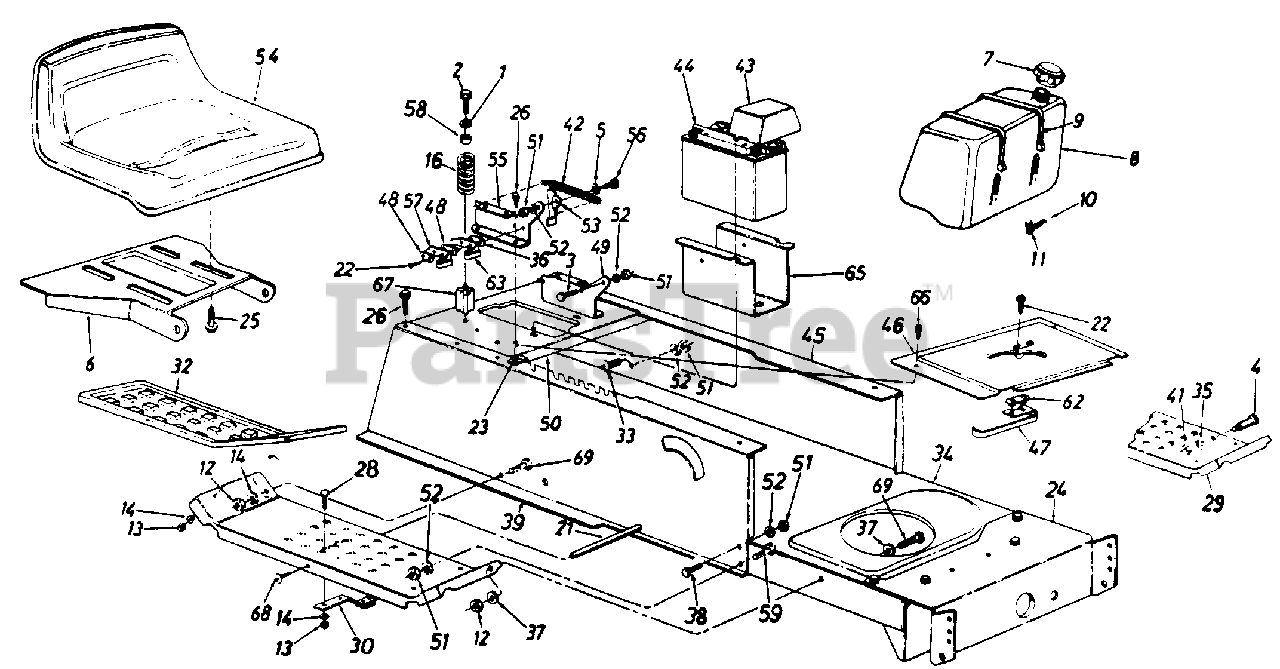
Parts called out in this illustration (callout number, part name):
1	Fl-Wash. .344" I.D. x .875"
2	Hex Wash. Hd. Tap Scr. 5/16-18 x 3.25" Lg.
3	Shld. Bolt .437" Dia. x .162"
4	Shld. Bolt .50" Dia. x .84"
5	Spr. Wash. .445" I.D. x .75
6	Seat Pivot Bracket
7	Fuel Cap
8	Fuel Tank
9	Tie Strap
10	Fuel Line
12	Hex Nut 1/4-28 Thd.
13	Hex Nut 1/4-20 Thd.
14	L-Wash. 1/4" I.D.
16	Compression Spring
21	Running Board Rod
22	Hex Wash. Hd. AB-Tap Scr. #8 x .50" Lg.
23	Speed Nut #10Z
24	Front Pivot Brkt.
25	Hex Tap Scr. 3/8-16 x .75"
26	Hex Wash. Hd. AB-Tap Scr. 5/16 x .75" Lg.
28	Carriage Bolt 1/4-20 x .62"
29	Running Board (R.H. & L.H.)
30	Blade Brake Ass'y.
32	Rubber Foot Pad - L.H.
33	Truss Mach. Scr. 5/16-18 x .75" Lg.
34	Lower Frame
35	L-Wash. 3/8" I.D.
36	Insulator Boss Plate
37	Fl-Wash. .25" I.D. x .625" O.D.
38	Hex Bolt 5/16-18 x .75" Lg.
39	Upper Frame - R.H.
41	Hex Nut 3/8-16 Thd.
42	Extension Spring 5.31" Lg.
43	Battery Cover
44	12-V Battery (275 Cold Crank Amps)
45	Upper Frame - L.H.
47	Reverse Safety Switch
48	Insulator Plate
52	L-Wash. 5/16" I.D.
53	Seat Lift Brkt.
56	Shld. Bolt .437" Dia. x .268"
57	Spring Switch
59	Hex Wash. TT-Tap Scr. 5/16-18 x 7/8" Lg.
62	Insulator Nut Plate
63	Safety Switch (Seat)
65	Battery Tray
66	Truss Mach. B-Tap Scr. #10 x .5" Lg.
67	Spring Spacer
68	Pan Hd.Cutting Scr. 5/16-18 x .75" Lg.
69	Hex Bolt 1/4-28 x .75" Lg.
